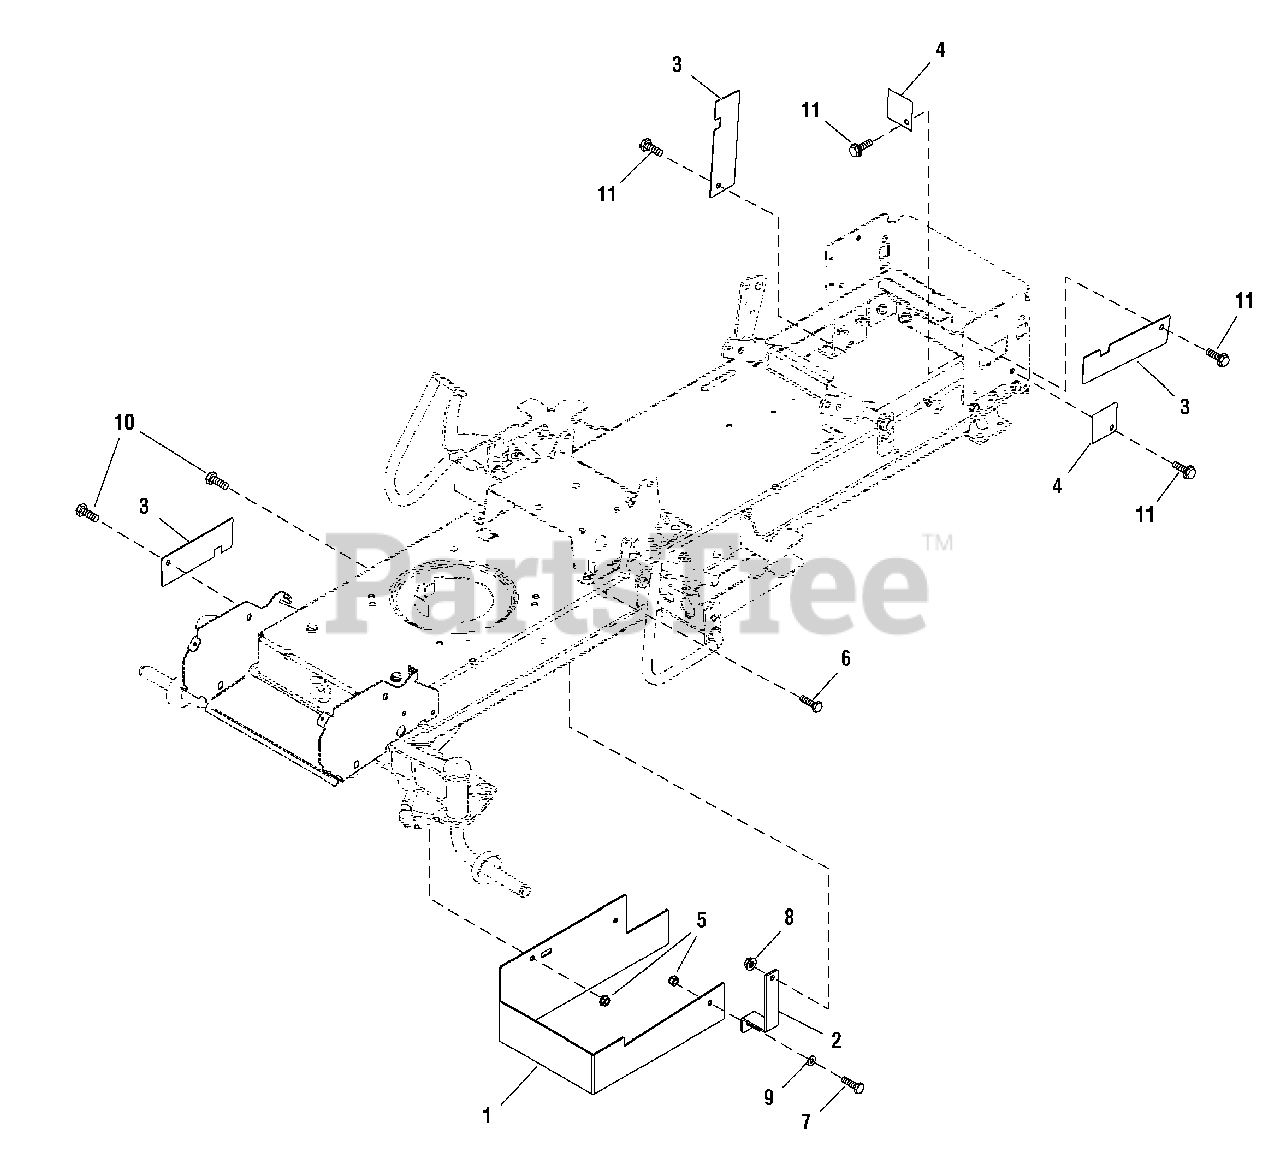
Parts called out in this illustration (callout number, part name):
1	GUARD, Clutch
2	SUPPORT, Guard
3	GUARD, Rear Pulley
4	GUARD, Rear
5	NUT, Hex Flange, 5/16-18
6	CAPSCREW, Dog Point, SEMS, 1/4-20 x 3/4
7	CAPSCREW, Hex Head, 1/4-20 x 1/2
8	NUT, Hex Lock ESNA, 1/4-20
9	WASHER, 1/4
10	CAPSCREW, Hex, 5/16-18 x 3/4
11	CAPSCREW, Hex Head, Flange Whiz Lock, 5/16-18 x 3/4
